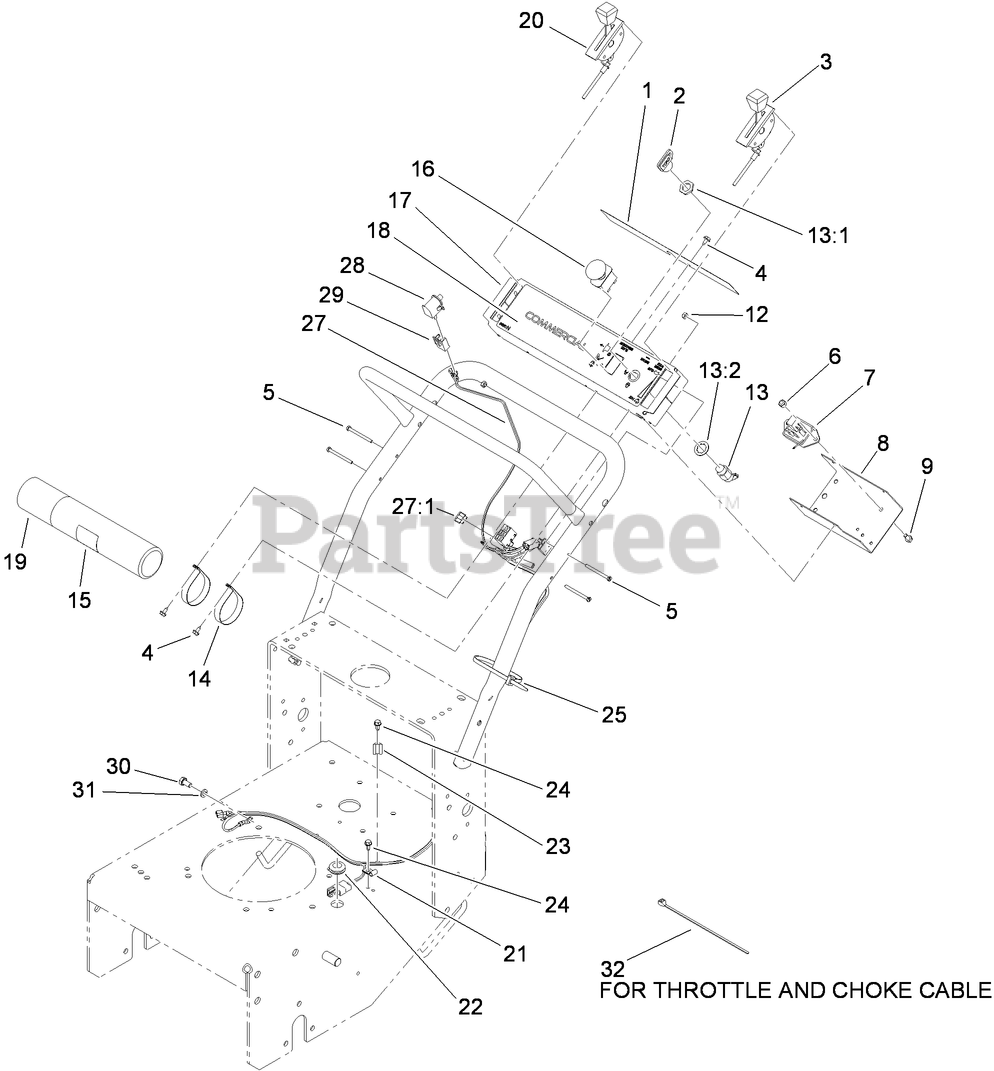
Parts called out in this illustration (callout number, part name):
1	DECAL-DANGER
2	KEY-IGNITION
3	CABLE-THROTTLE
4	SCREW-HWHTF
5	SCREW-SHH
6	NUT-LOCK, NI
7	MODULE-DELAY
8	PANEL-BOTTOM
9	SCREW-HH
12	NUT-LOCK, NI
13	SWITCH-ON / OFF
13:1	NUT-HH
13:2	WASHER-TOOTH, INTERNAL
14	CLAMP-R
15	TUBE-MANUAL
16	SWITCH-PTO
17	PANEL-CONTROL
18	DECAL-PANEL, CONTROL
19	CAP-HOUSING
20	CABLE-CHOKE
21	CLIP-CLOSED, INSULATED
22	GROMMET
23	CLAMP-R
24	SCREW
25	TIE-CABLE
27	HARNESS-WIRE
27:1	FUSE-BLADE, 7.5 AMP
28	SWITCH-BAIL
29	CONNECTOR-BODY
30	SCREW-HH
31	WASHER-LOCK
32	TIE-CABLE
